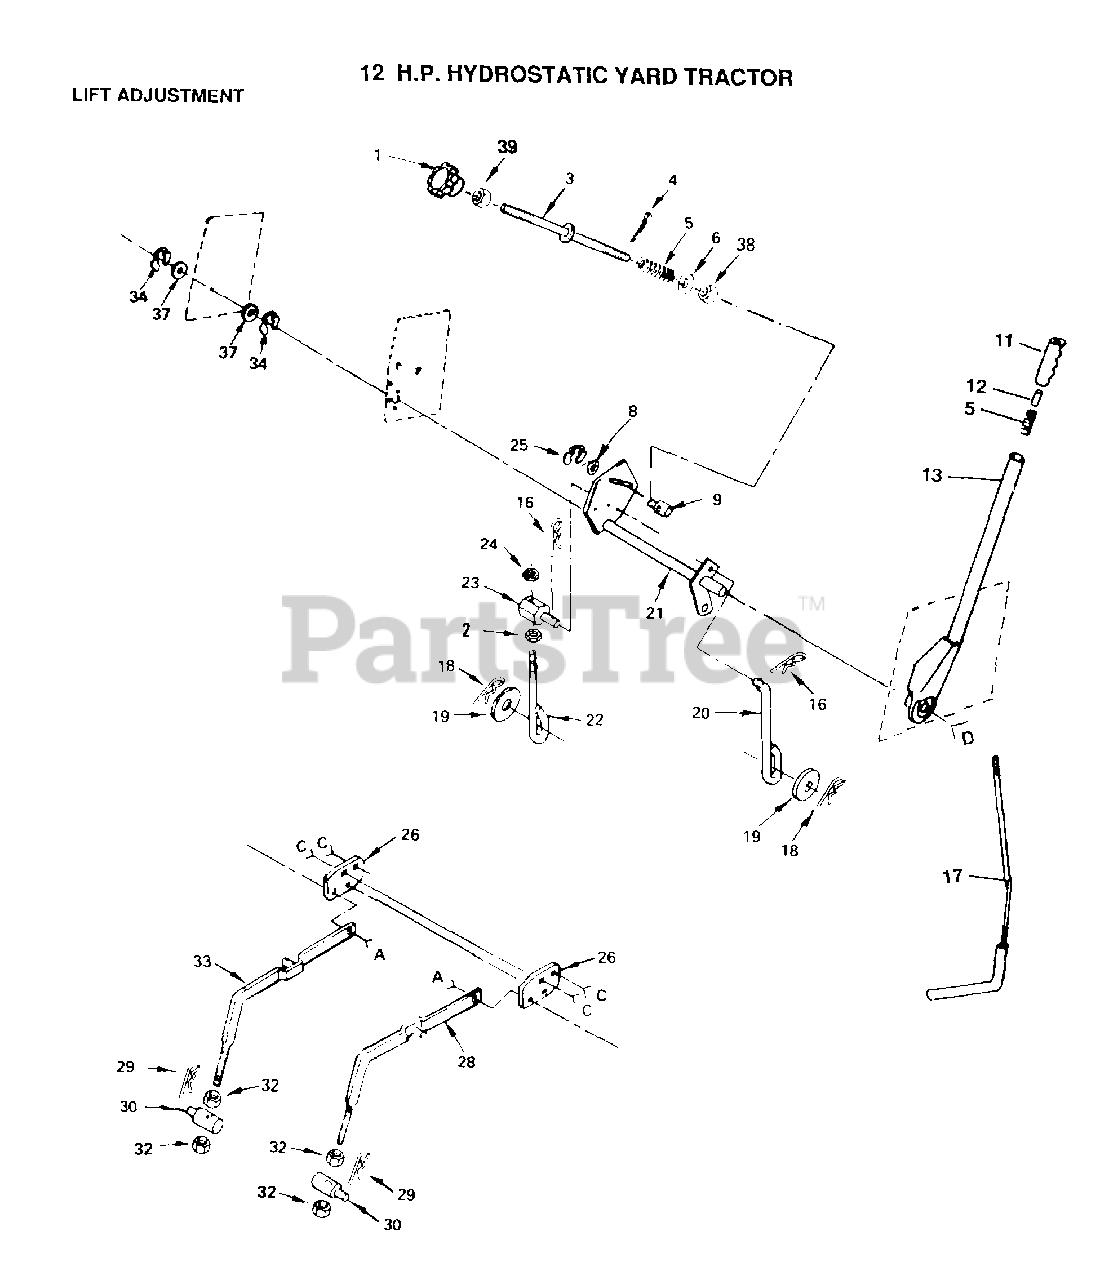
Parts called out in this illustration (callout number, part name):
1	HDLE ADJ LIFT
2	NUT
3	ROD LIFT LT
5	SPRING T
6	WASHER
8	WASHER
9	TRUNION LT
11	GRIP
17	LEVER ROD LT
18	SPRING.RETAINER
22	PIVOT PIN T
25	KLIP RING
26	"BRACKET, SUSPE T"
28	RH SUSP ARM ASM
29	SPRING H
32	NUT, HEX FIN. 1/2 - 13
33	LH SUSP ARM ASM
34	E-RING
37	WASHER
38	NUT T
39	NUT
